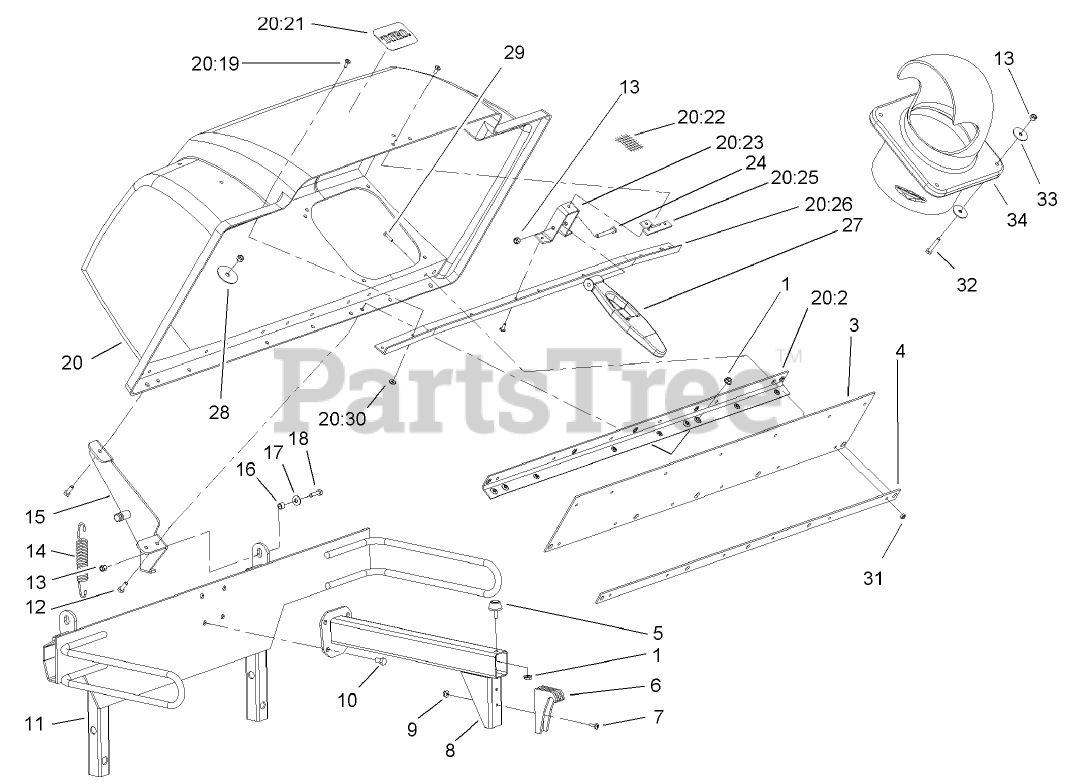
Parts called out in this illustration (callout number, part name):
1	NUT-HF
4	PLATE-BACKING
5	BUMPER
7	SCREW-PPH
8	BAG SUPPORT ASM
9	Nut
10	SCREW-HH
11	BAGGER UPRIGHT ASM
12	SCREW-HH
13	NUT-LOCK, NI
14	SPRING-EXTENSION
15	HINGE ASM
16	SPACER
17	WASHER-FLAT
18	SCREW-HH
19	RIVET-BLIND
20	Hood ASM
20:2	STIFFENER-BAGGER, TOP
20:19	RIVET-BLIND
20:20	Top-Bagger
20:21	DECAL
20:22	SCREEN-BAGGER
20:23	ANCHOR-LATCH
20:25	REINFORCEMENT-LATCH
20:26	SUPPORT-SCREEN
20:30	WASHER-FLAT
24	SCREW-HH
28	WASHER
29	SCREW-HEAD, TRUSS
31	NUT-LOCK, NI
32	SCREW-HH
33	WASHER-FLAT
34	Tube-Bagger, Upper
